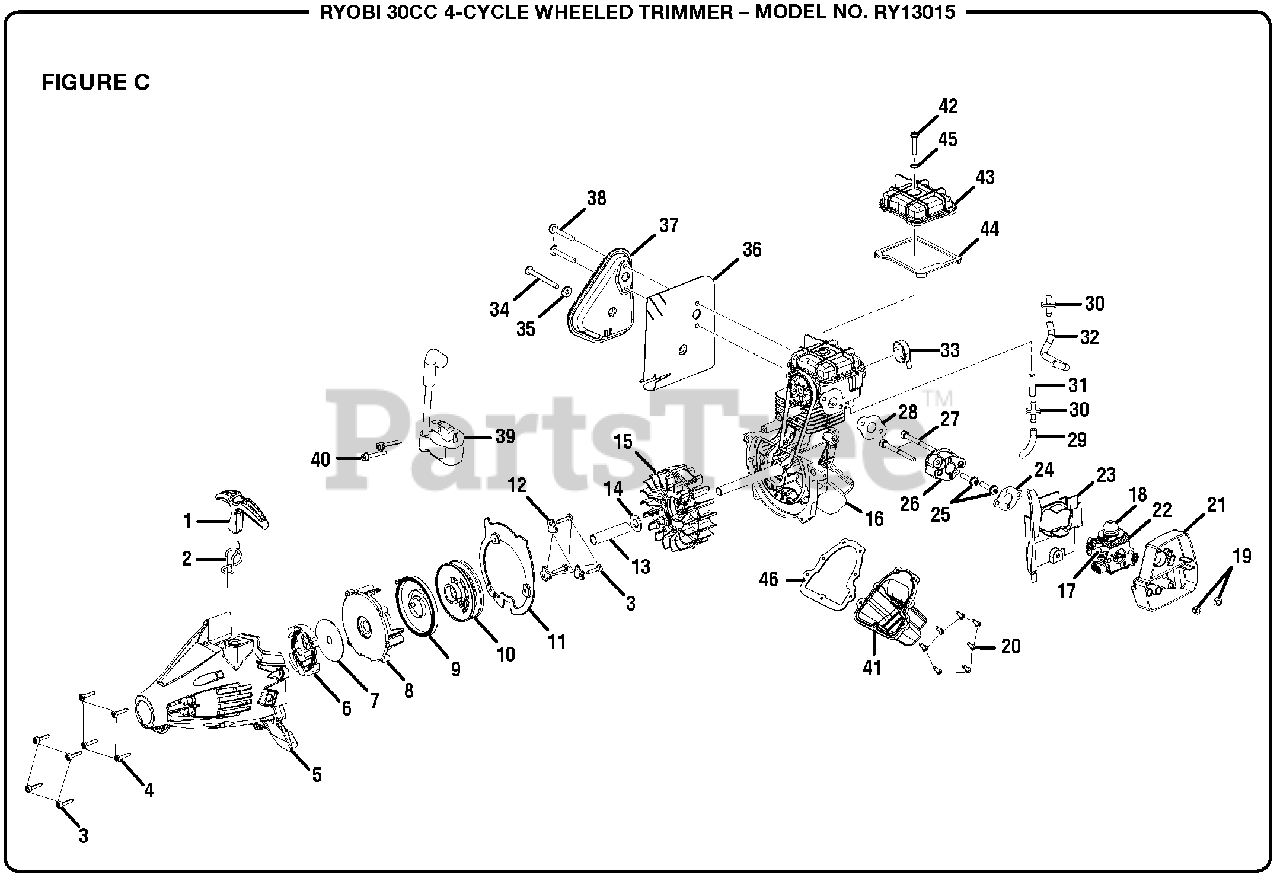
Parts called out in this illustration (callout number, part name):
1	Starter Grip
2	Starter Rope
3	Screw (M4 x 18 mm)
4	Screw (M4 x 16 mm)
5	Starter Housing Assembly
6	Clutch Assembly
8	Starter Baffle
9	Spring & Container
12	Pulley Retainer
13	Spacer Tube
14	Washer
15	Flywheel Assembly
16	Short Block Assembly (Inc. Key Nos. 20 and 42-46)
17	Choke Lever
18	Primer Bulb
19	Hex Nut (M5)
20	Screw (M4 x 12 mm)
21	Air Box Base
22	Carburetor Assembly (Inc. Key Nos. 17-18)
23	Air Baffle
24	Carburetor Gasket
25	Screw (M5 x 23 mm)
27	Bolt (M5 x 58 mm)
28	Heat Dam Gasket
29	Breather Hose
30	Check Valve
31	Breather Hose
32	Breather Hose
33	Breather Fitting
36	Muffler Gasket
37	Muffler Assembly
38	Muffler Bolt (M5 x 42 mm)
39	Ignition Module
40	Screw (M4 x 19 mm)
42	Screw (M4 x 27 mm)
43	Cam Cover
